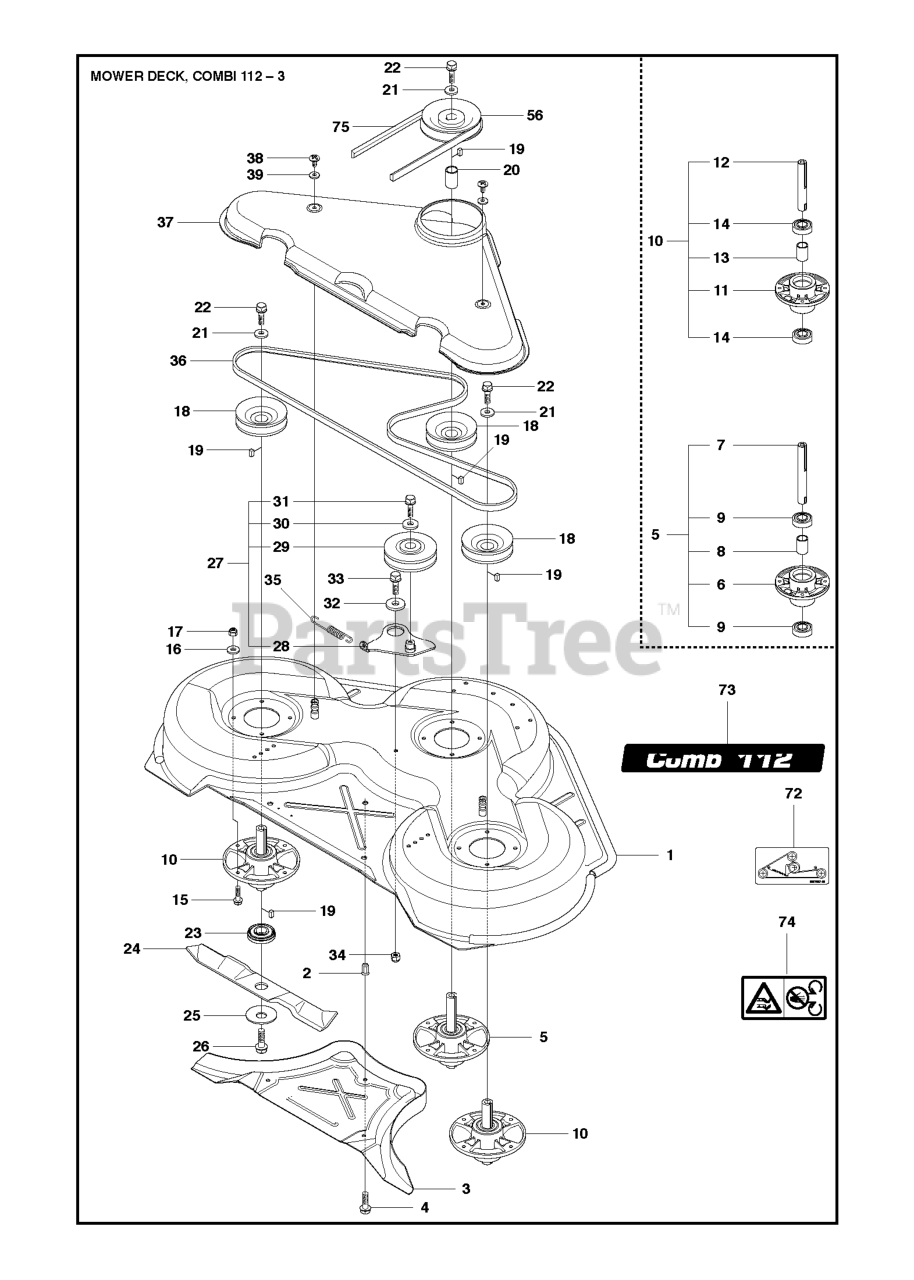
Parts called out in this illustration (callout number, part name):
6	BEARING HOUSING
9	BALL BEARING
11	BEARING HOUSING
14	BALL BEARING
16	WASHER BRB 8.4X17
17	LOCKNUT M8
28	BELT TENSIONING ARM
32	WASHER
34	LOCKNUT M8
37	BELT COVER
